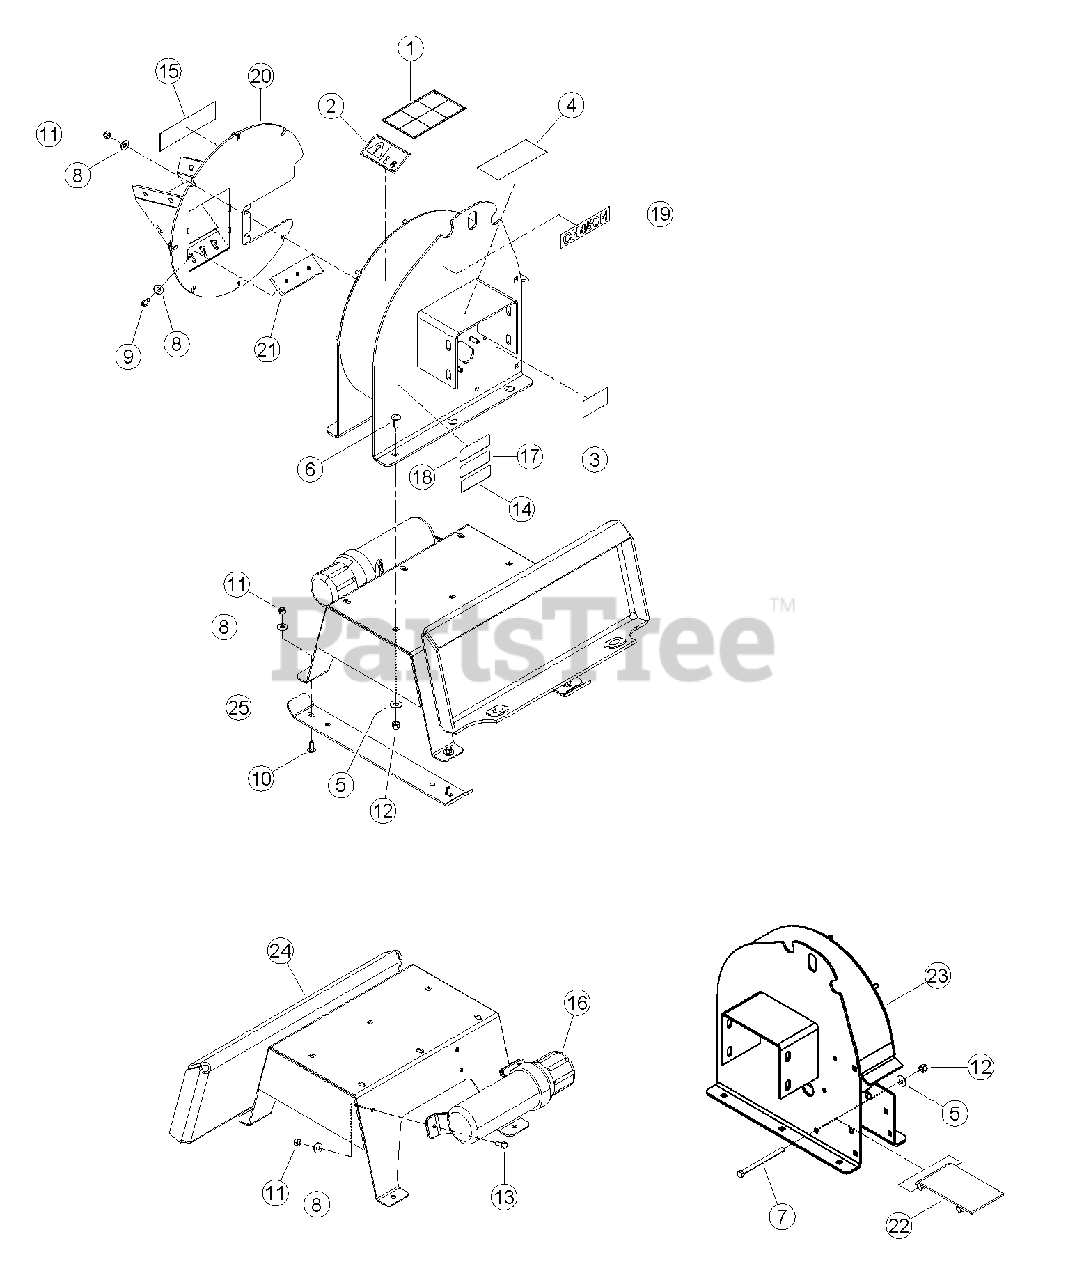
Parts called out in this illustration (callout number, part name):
1	DECAL, OPERATING INSTRUCTIONS ISO
2	DECAL, MAINTENANCE ISO
3	DECAL, DANGER
4	DECAL, MUTILINGUAL MANUAL
5	WASHER, 3/8 FLAT ZP
6	BOLT, 3/8 X 1 CRG GR5 NC ZP
7	BOLT, 3/8 X 5 HEX HD GR5 ZP
8	WASHER, 5/16 FLAT ZP
9	BOLT, 5/16 X 5/8 HEX HD GR5 ZP
10	BOLT, 5/16 X 7/8 CRG GR5 NC ZP
11	NUT, 5/16 NE NYLOCK ZP
12	NUT, 3/8 NE NYLOCK ZP
13	BOLT, 5/16 X 7/8 HEX HD NC GR5 ZP
14	DECAL, SERIAL NUMBER
15	DECAL, ECHO BEARCAT 6.82 X 1.90
16	CONTAINER, MANUAL
17	DECAL, ATLANTIC BRIDGE LTD INFO
18	DECAL, CH450H INFORMATION
19	DECAL, MODEL CH450H
20	WELDMENT, DISK COVER
21	ANVIL, CHIPPER
22	WELDMENT, CHIP DEFLECTOR
23	WELDMENT, CHIPPER HOUSING
24	WELDMENT, BASE
25	PLATE, BASE SKID
